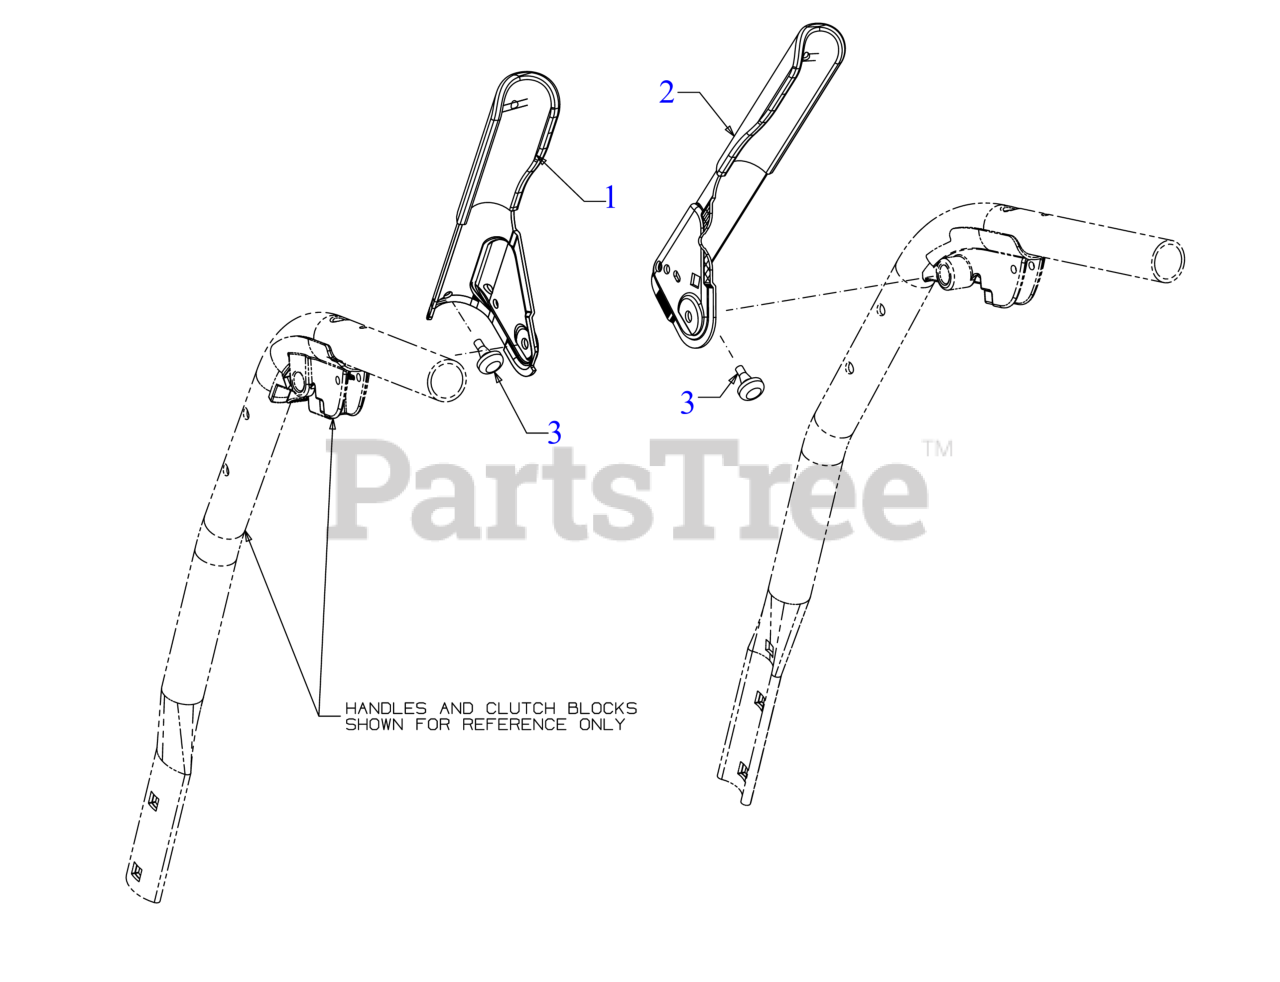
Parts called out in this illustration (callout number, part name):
1	ENGAGEMENT HANDLE (RED) (LH)
2	HANDLE ASSEMBLY (RH)
3	RUBBER BUMPER
